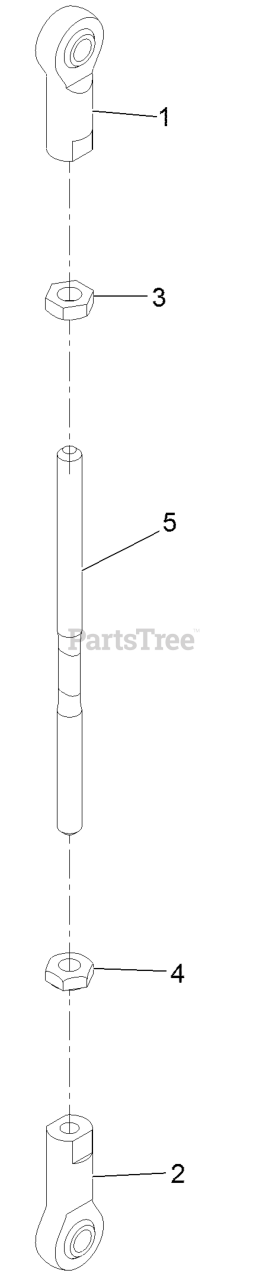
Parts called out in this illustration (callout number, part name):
1	ROD END-BALL JOINT
2	JOINT-BALL, LH
3	NUT-JAM
4	NUT-JAM
